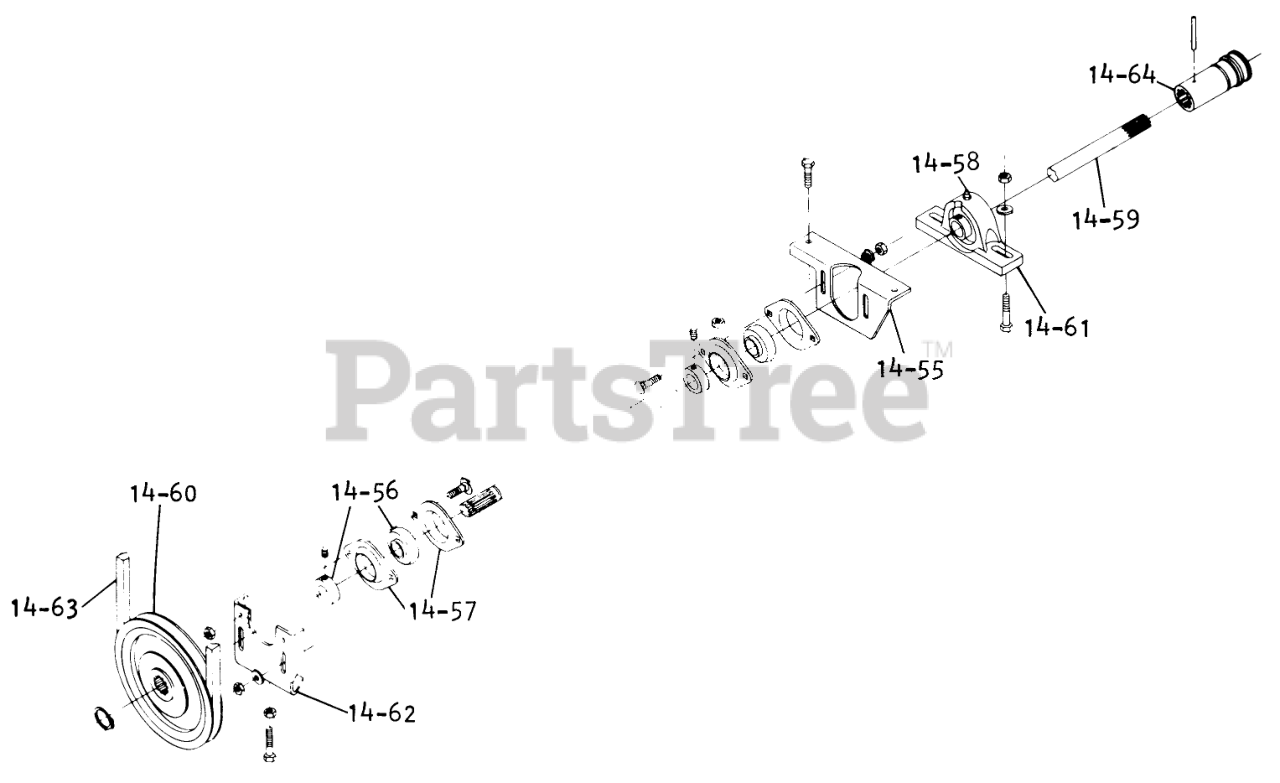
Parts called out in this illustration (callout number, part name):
14-55	Bracket
14-56	BEARING
14-57	FLANGE
14-58	ZERK 90DEGREE
14-59	SHAFT-DRIVE
14-60	Pulley
14-61	Assembly Bearing
14-62	Bearing Bracket
14-63	BELT PTO
14-64	QUICK COUPLER ASSY
